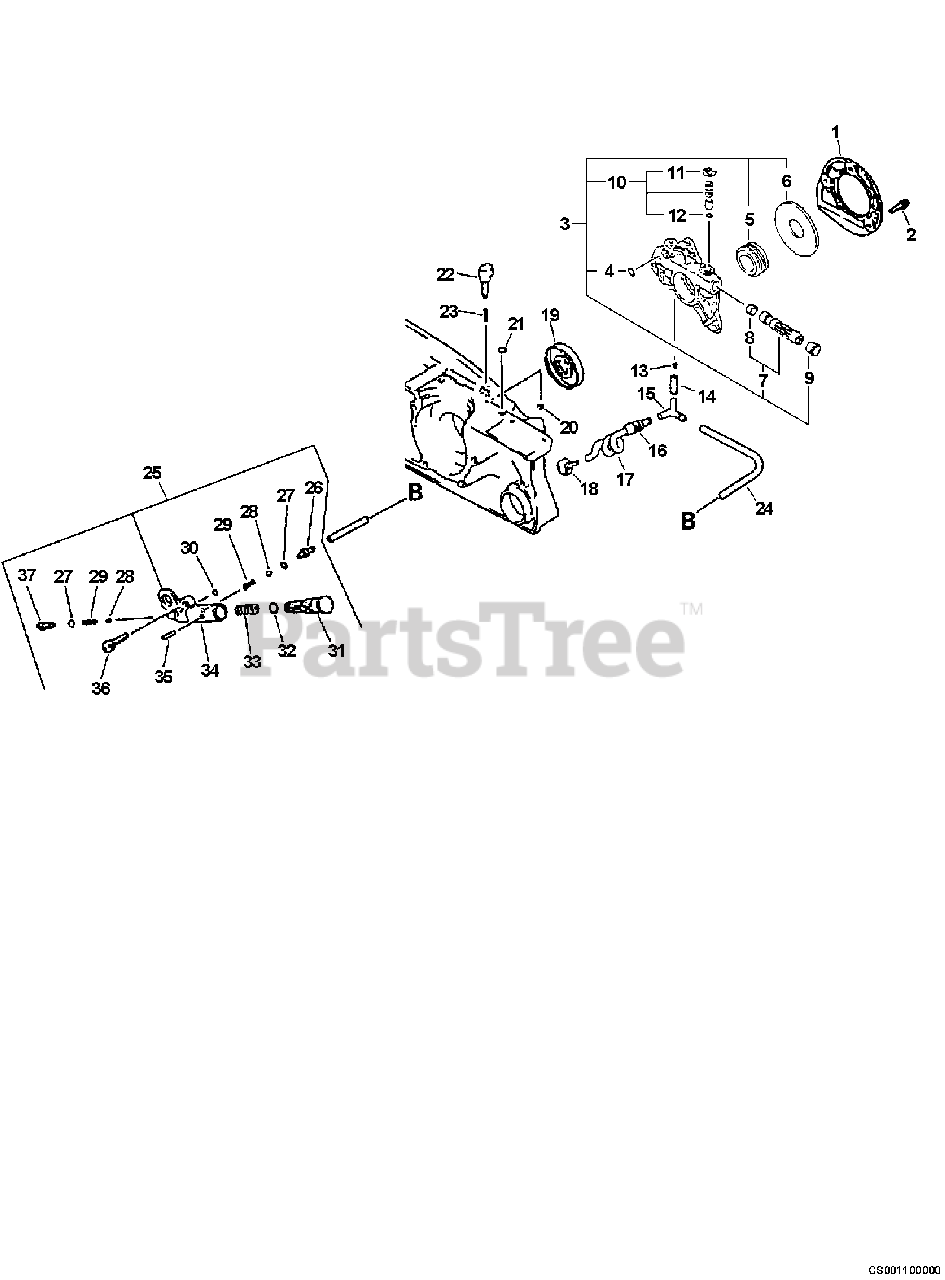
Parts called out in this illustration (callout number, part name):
1	COVER, OIL PUMP
2	SCREW - 4X14
3	AUTO-OILER ASSY
4	O-RING - 3
5	GEAR - WORM
6	WASHER - 12
7	PLUNGER KIT
9	CAP, PLUNGER
10	CONTROL PIN ASSY
13	CLIP - 6.5
14	PIPE - 3X6X20 -- BLACK
15	CONNECTOR, PIPE
17	PIPE - OIL
18	FILTER, OIL
19	SEAL, OIL
20	RING, RETAINING - 3
21	O-RING - 3
22	DIAL, AUTO-OILER
24	PIPE - 3X6X210 -- BLACK
25	OIL PUMP ASSY
28	VALVE, BALL
30	O-RING - 3
31	PISTON, OIL PUMP
32	O-RING - 7
34	BODY, OIL PUMP
35	PIN - SPRING -- 2X16
36	SCREW - 5X20
37	ADAPTER, OIL PUMP
